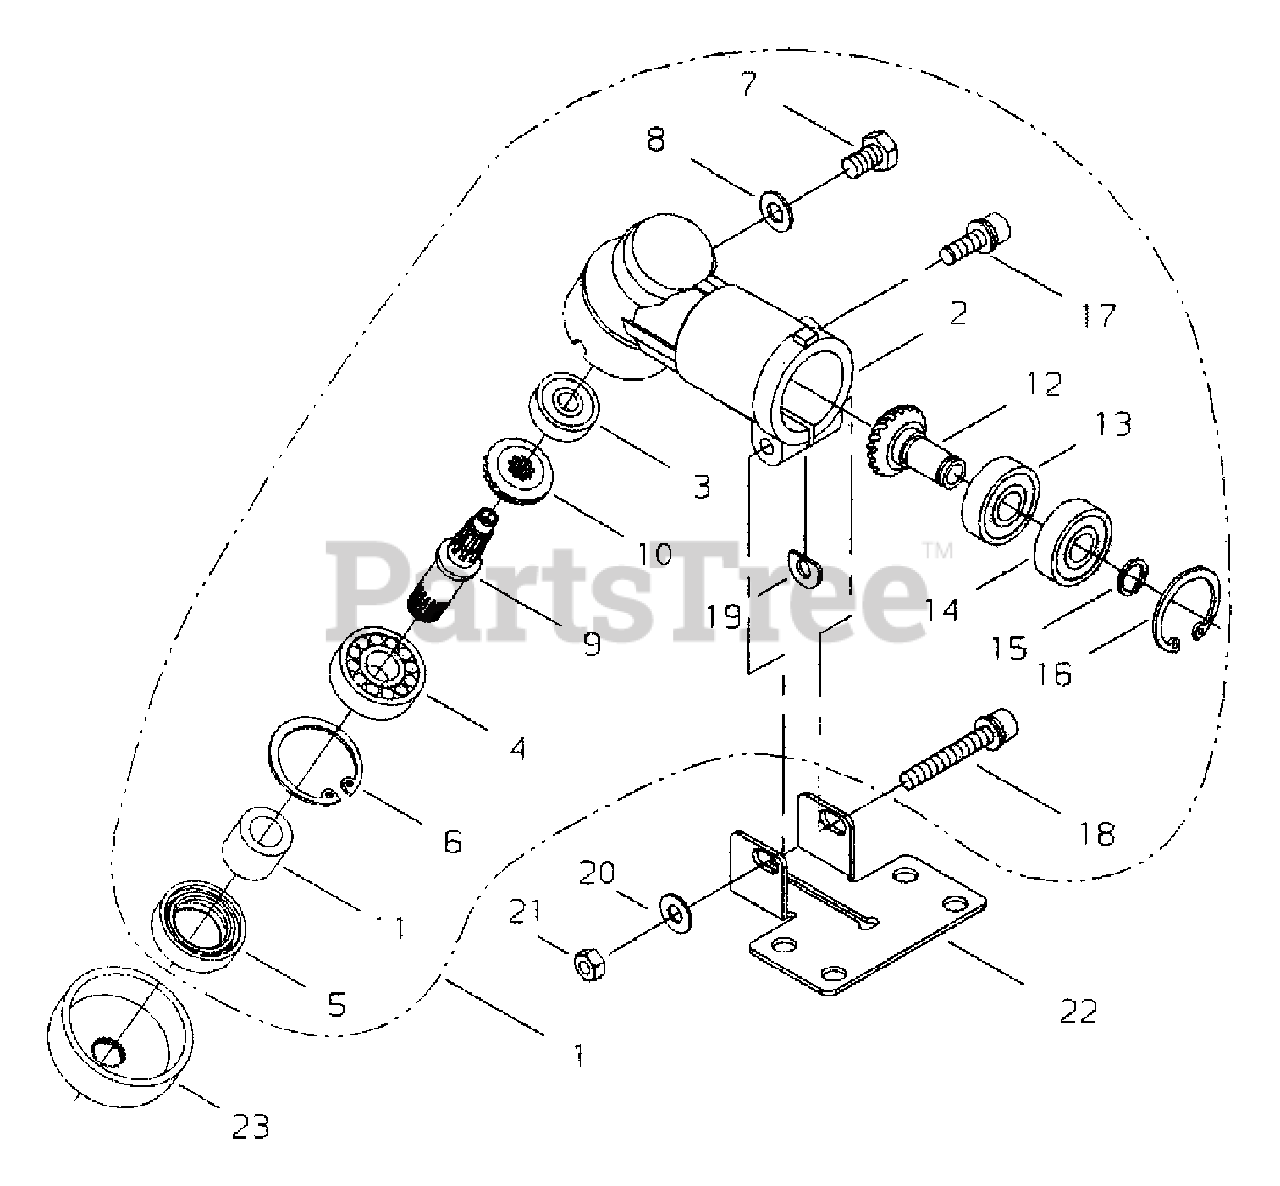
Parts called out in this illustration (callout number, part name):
1	GEAR CASE SUB ASSY
2	CASE, GEAR
3	BEARING, BALL - 626
4	BEARING, BALL - 6000
5	SEAL, OIL
6	RING, RETAINING - 26
7	BOLT - 6X10
8	WASHER
9	GEAR - SHAFT
10	GEAR - BEVEL
11	COLLAR
12	GEAR - SHAFT
13	BEARING, BALL - 608
14	BEARING, BALL - 608ZZ
15	RING, RETAINING
16	RING, RETAINING - 22
17	SCREW - 5X16
18	SCREW - 5X35
19	SHIM
20	WASHER - 5
22	CLAMP - LOWER
23	HOLDER
